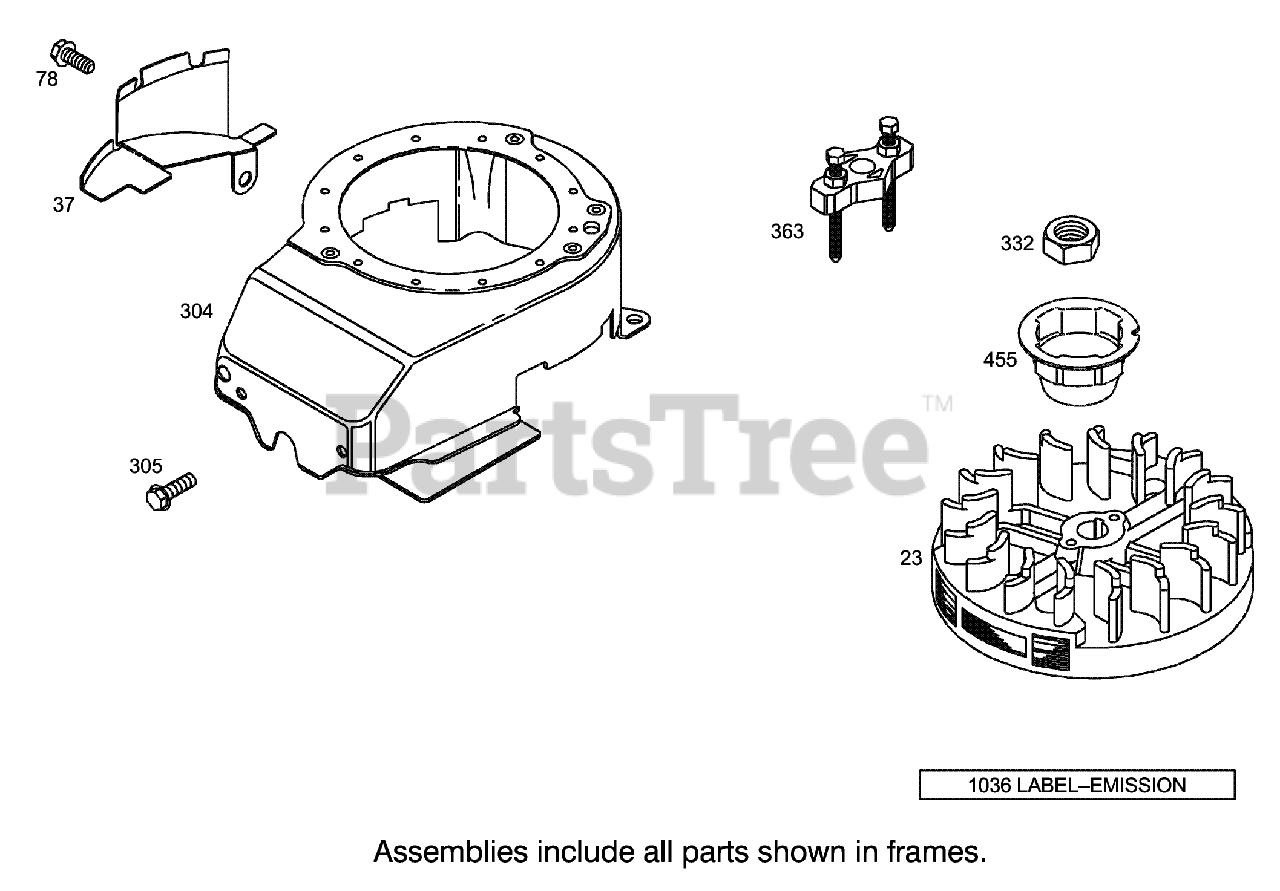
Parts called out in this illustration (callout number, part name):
23	Flywheel
37	Guard-Flywheel
78	Screw
304	Housing-Blower
305	Screw
332	Screw
363	Puller-Flywheel
455	Cup/Screen ASM
1036	Label-Emissions
